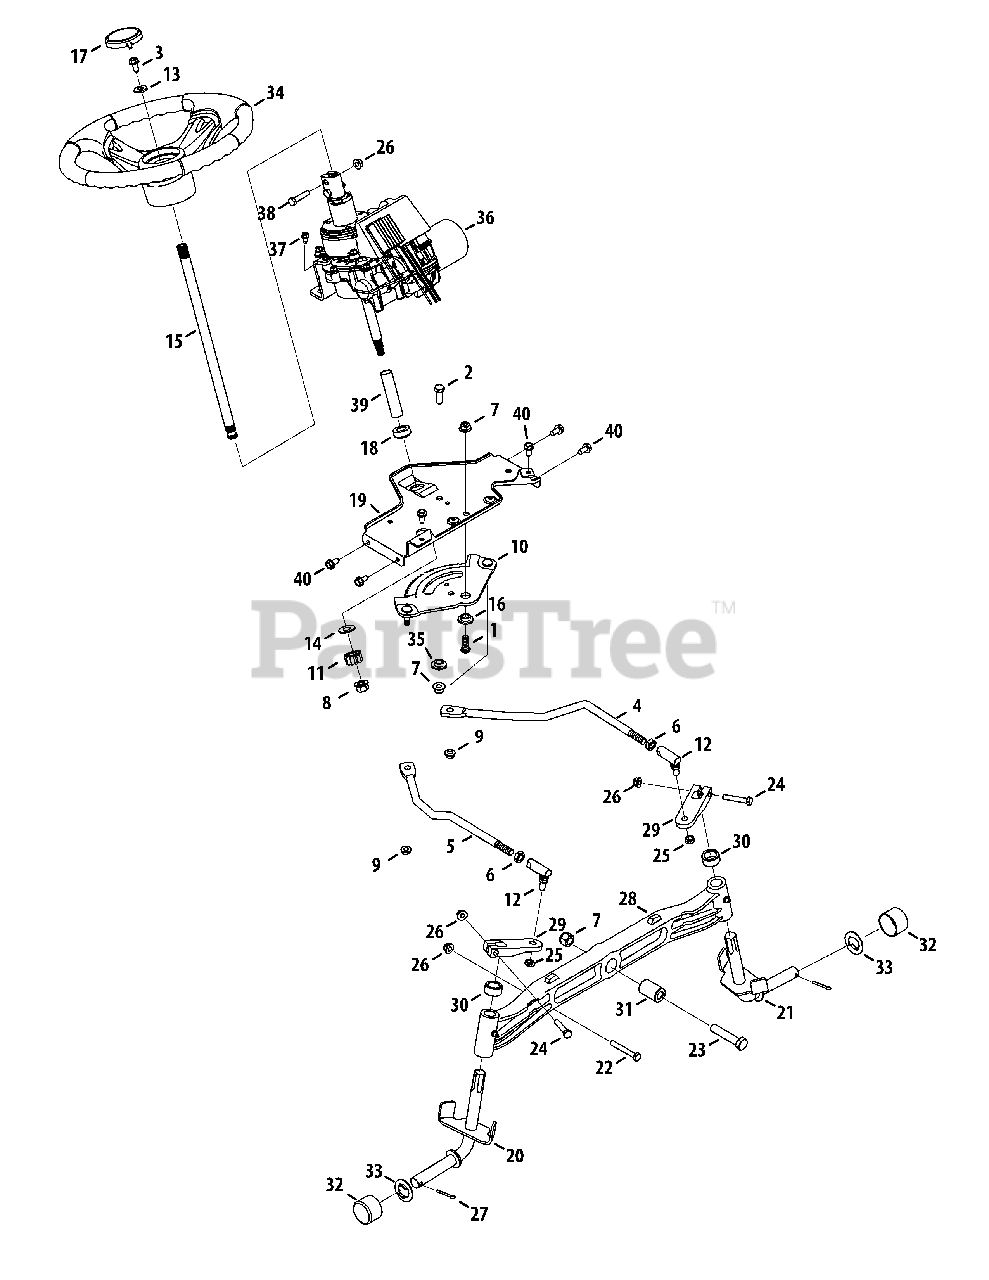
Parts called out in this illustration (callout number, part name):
1	Hex Screw, 3/8-16, 1.00, Gr5, Spec
2	Hex Screw, 3/8-16, 1.00, Gr5, Std
3	Hex Screw, 5/16-18, .875, Gr5, Lock
4	Link, Drag LH
5	Link, Drag RH
6	Nut, Jam, 7/16-20, Gr2
7	Nut, Flange Lock, 3/8-16, Grf,
8	Nut, Flange Lock, 7/16-20, Grb, Lock
9	Nut, Flange Lock, 5/16-18, Gr5, Sd Lk
10	Gear, Steering, 11/90 Ratio
10	Gear, Steering
11	Gear, Pinion, Steering
12	Ball Joint, 7/16-20, Lock
13	Washer, Flat, .406 x .875 x .105
14	Washer, Flat, .51 x 1.12 x .06
15	Shaft, Steering, .625 OD x 14, Cub
16	Spacer, Shoulder, .385x 1.25 x .3025
17	Cover, Steering Wheel, Cub Cadet
18	Bearing, Flange, Hex 5/8 Pm
19	Bracket, Support, Steering
20	Axle Ass’y, RH .750 Dia.
21	Axle Ass’y, LH .750 Dia.
22	Hex Screw, 5/16-18, 2.25, Gr5, Std
23	Hex Screw, 3/8-16, 2.50, Gr5, Std
24	Hex Screw, 5/16-18, 1.75, Gr5, Std
25	Nut, Hex Lock, 3/8-24, Grb
26	Nut, Flange Lock, 5/16-18, Grf
27	Pin, Cotter, 5/32, 1.25
28	Axle, Pivot Bar, Cast
29	Steering, Block
30	Spacer, .71 ID x .125 OD x .56
31	Spacer, .385 x 1.00 x 1.5075
32	Cap, Bumper
33	Washer, Flat, .350 x 1.559 x .062
34	Wheel, Steering, 3 Spoke, Softgrip
35	Spacer, .38 x 1.375, Spec
36	Transmission Steering Assembly, EPS
37	Screw, Self-tapping, 1/4-20 x .625
38	Hex Screw, 5/16-18 x 1.375, Gr5, Std
39	Spacer, .625 x .750 x 3.11
40	Screw, Self-tapping, 5/16-18, .750,
